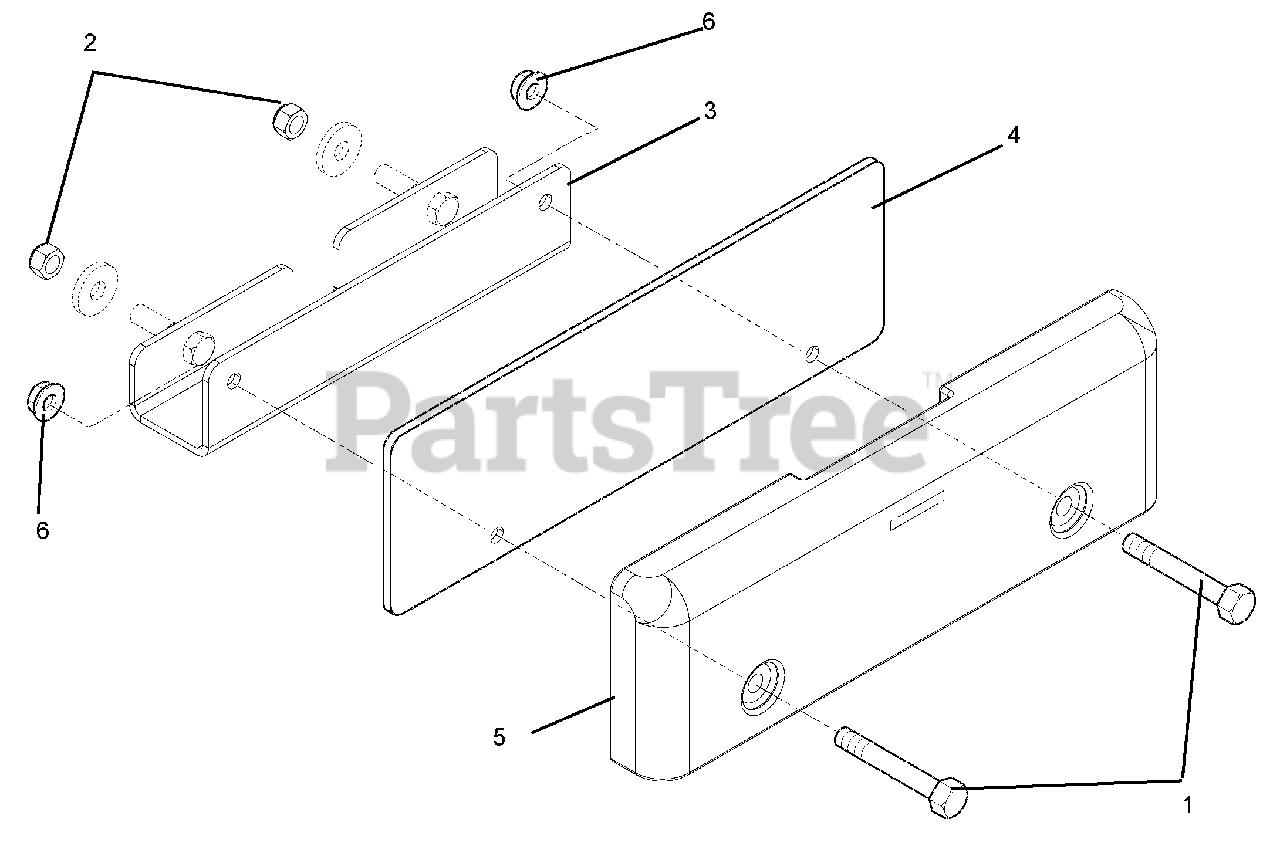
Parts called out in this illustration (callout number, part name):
1	@BLT-HEX .50-13X3.50 GR5 YWZC
2	@NUT-LK-NYL-FLG .63-11 YWZC
3	BKRT, ZOOM BAGGER WGT
4	WEIGHT, BURNOUT
5	WEIGHT, CAST IRON
6	@NUT-LK-NYL-FLG .50-13 YWZC
